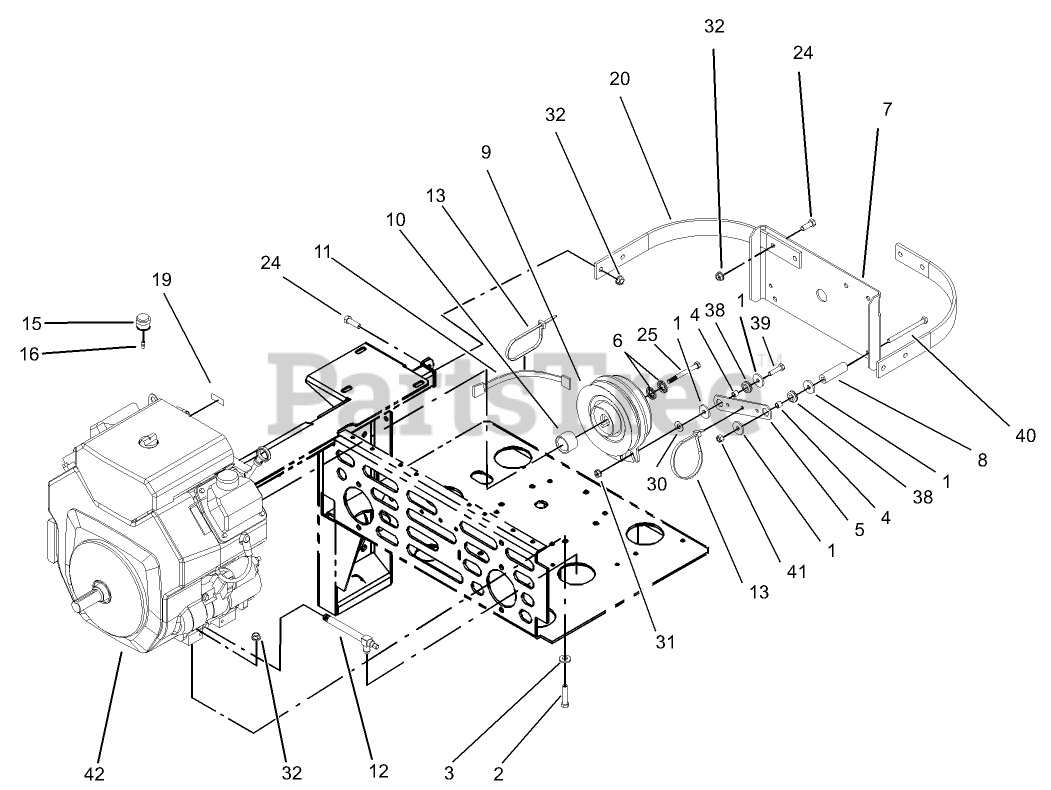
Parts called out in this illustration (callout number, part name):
1	WASHER
2	SCREW-HH
3	WASHER-BELLEVILLE
4	SPACER
5	STRAP-CLUTCH, BRAKE
6	WASHER-SPRING
7	GUARD-CLUTCH
8	SPACER-ANCHOR, CLUTCH
9	Clutch
10	SPACER-CLUTCH
11	Harness, Efi Clutch Pigtail
12	VALVE-OIL DRAIN, LONG
13	TIE-PLASTIC
15	INDICATOR-FILTER, AIR
16	ADAPTER-INDICATOR
20	BRACKET-GUARD, TOP
24	SCREW-HH
25	SCREW-HH
30	WASHER-FLAT
31	NUT-HF
32	NUT-HHF, WHIZ
38	GROMMET
39	SCREW-HH
40	SCREW-HH
41	NUT-LOCK, NI
